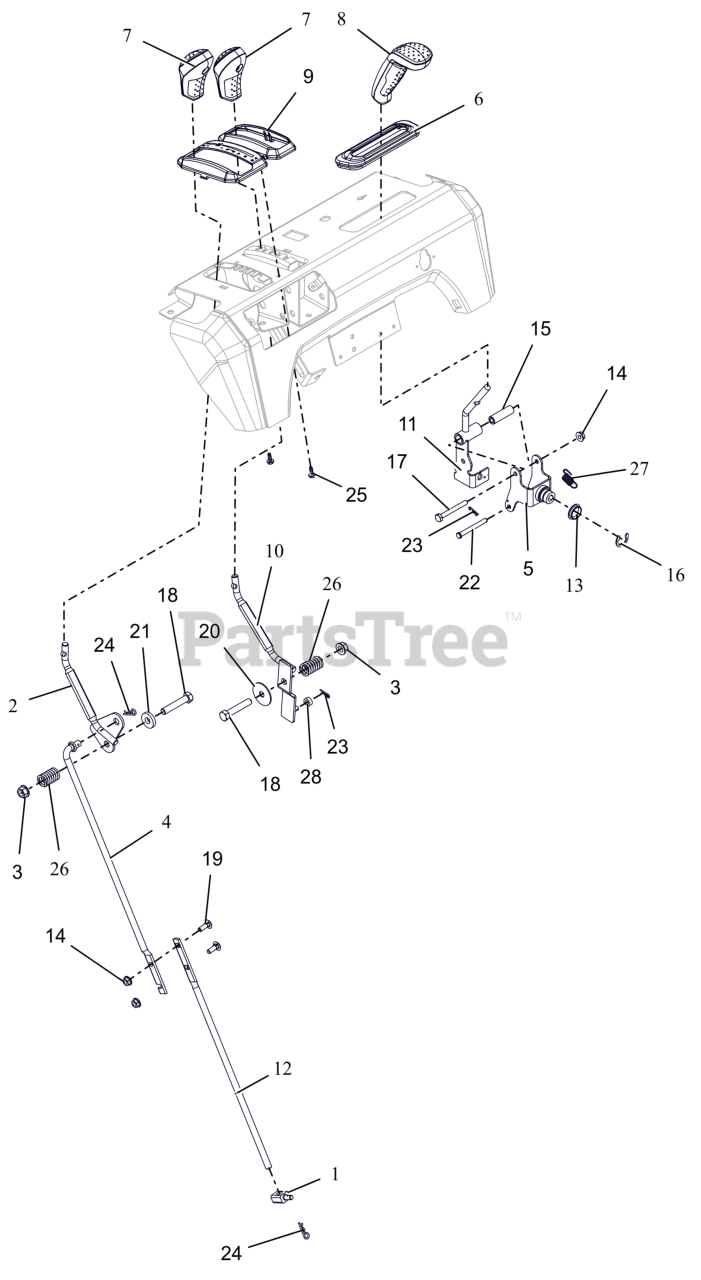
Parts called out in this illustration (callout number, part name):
1	PIVOT,SHIFT ROD .375-16(TRUNN)
2	WELDMENT,LG DASH SPEED CONTROL
3	NUT-LK-TOP-FLG .38-16 ZC120
4	ROD, SHIFT - UPPER
5	WELDMENT, CONTROL BRACKET
6	GROMMET, BOOT, QUICK TURN
7	KNOB, CONTROL, DASH
8	HANDLE, QUICK TURN, ASM
9	BEZEL, SHIFT - FRICTION SNOW
10	WELDMENT,LG DASH DEFL CONTROL
11	WELDMENT, CONTROL LEVER
12	ROD, SHIFT-LOWER (LG DASH DLX)
13	BUSHING, POLYLINER-.75 SNAPIN
14	NUT-LK-CTR-FLG .25-20 ZC120
15	BSHG, SLV .265X.505X1.665
16	E-RING .750X.050
17	BLT,HEX .25-20X2.25 G5 ZCC
18	BLT,HEX .38-16X2.00 G5 ZCC
19	BLT, RHSN .25-20X.750 G5 ZCC
20	WSHR,FLT .380X1.50X.062 ZCC
21	WSHR, FLT .406X1.00X.188 ZCC
22	PIN, CLEVIS - .25 X 2.25 ZCC
23	PIN, HAIR #178 .06X.77 ZCC
24	PIN, HAIR #213 .08X1.19 ZCC
25	SCR, PLASTIC #10X.50
26	SG-COMP .125X.781X1.250
27	SPRING-EXT .047X.438X1.45
28	BSHG-SLV .265X.500X.219
